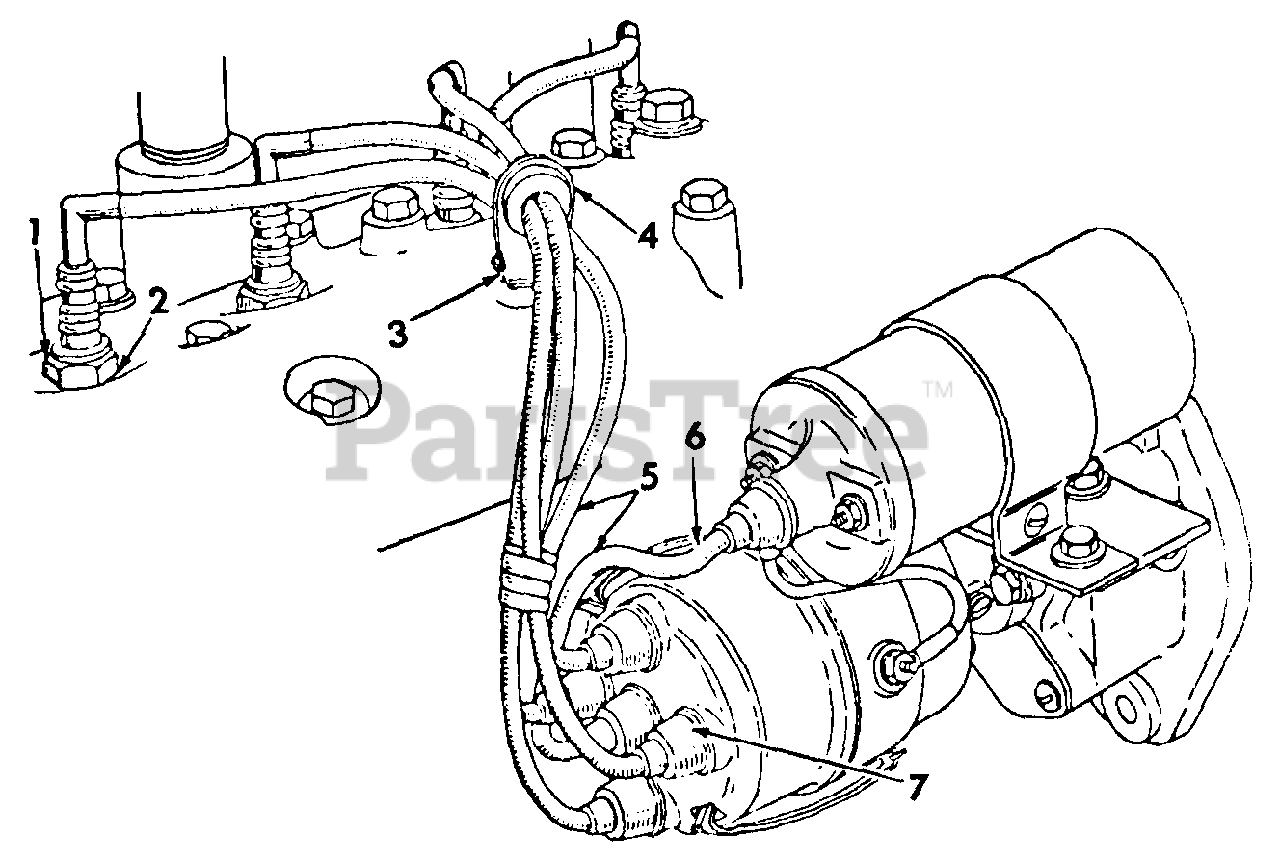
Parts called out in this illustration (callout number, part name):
1	PLUG, SPARK LIGHT SERVICE CHAMPION
2	GASKET, SPARK PLUG
3	BRACKET, SPARK PLUG CABLE
4	GROMMET, SPARK PLUG CABLE BRACKET
5	PACKAGE, IGNITION CABLE SERVICE
6	CABLE, COIL TO DISTRIBUTOR W/NIPPLES
7	NIPPLE, DISTRIBUTOR CAP TERMINAL
IH-RD6	PLUG, SPARK HEAVY SERVICE CHAMPION
